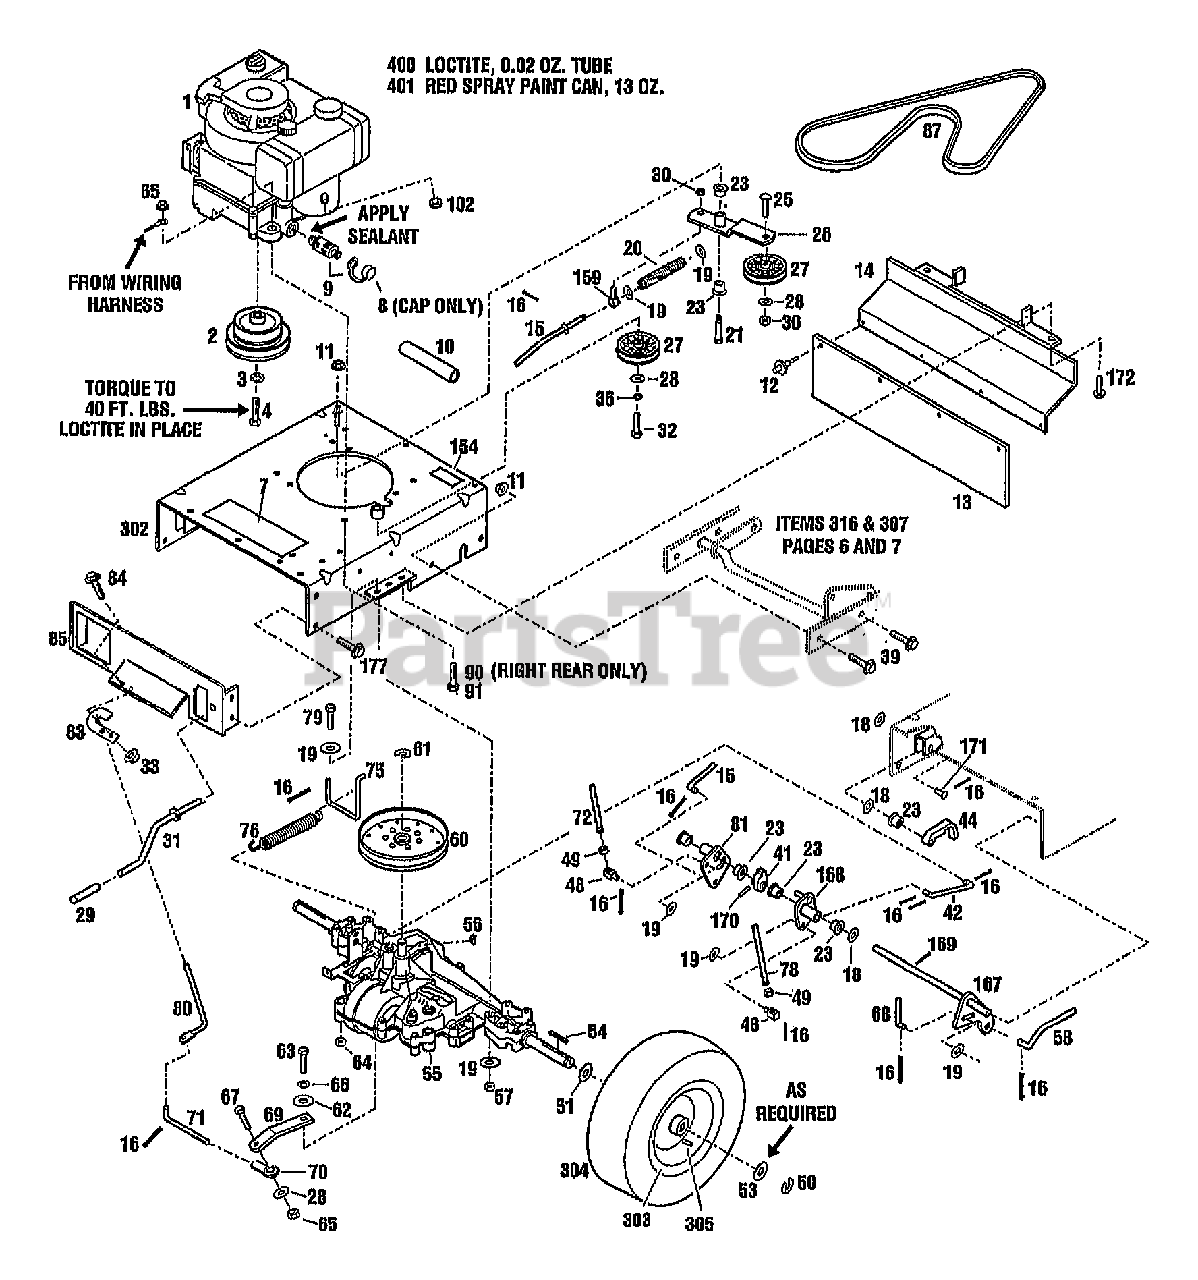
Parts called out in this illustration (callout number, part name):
1	ENGINE, 8.5HP MODEL 196707-0155 (34071,34074)
1	ENGINE, 8.5HP MODEL 196702-0142 (34073,34075)
2	PULLEY-ENGINE
3	WASHER-LK .438 ZP
4	SCR-HHC 7/16-20X1.75
7	DECAL-WARNING
8	CAP-OIL DRAIN
9	ASSM-OIL VALVE
10	HOSE-OIL DRAIN
11	NUT-HFLK 3/8-16 ZP
12	RIVET-POP 3/16 X 5/8
13	FLAP-SAFETY
14	BRACKET-FLAP
15	ROD-LOWER TRANS
16	PIN-COTTER .093X.625
18	WASHER-FLAT .88X.5X.06 ZP
19	WASHER-FLAT 5/16 SAE
20	SPRING-COMPRESSION
21	SCR-SHLDR 3/8-16
23	BUSHING-.5X.5 NYLON FLNG
25	SCR-CARR 3/8-16X1.75 G5 ZP
26	ASSM-IDLER ARM ZP
28	WASHER-FLAT 3/8 SAE
29	GRIP-PLASTIC
30	NUT-LOCK 3/8-16
31	ASSM-CRANK LIFT
32	SCR-HH 3/8-16X1.75 G5 ZP
33	NUT-HF/LK 1/4-20 ZP
36	WASHER-LK .375 @ DEPL
39	SCR-HFLK 3/8-16X1.00 ZP
41	CAM-INTERLOCK
42	ROD-LOWER BRAKE
44	LATCH-INTERLOCK
48	BLOCK-SWIVEL ZP
49	NUT-HEX JAM 5/16-18
50	RING-RET."E".577 ID
51	WASHER-1.5X.755X.062
53	WASHER-1.25X.765X.049
54	KEY-.188 SQ X 2.25
55	TRANSMISSION ASSEMBLY, MODEL 915-027 (SEE GRIDS E-5, E-6 FOR BREAKDOWN)
56	KEY-WOODRUFF .188X.75
57	NUT-TOP/LK 5/16-18 ZP
58	ROD-LOWER BLADE
60	PULLEY-TRANSAXLE
61	RING-RETAIN .625 ID
62	WASHER-FLAT 1/4 SAE
63	SCR-HH 1/4-28X.75 G5 ZP
64	NUT-HFLK 5/16-18 ZP
65	NUT-H/LK 3/8-16
66	WASHER-LK .25 ZP
67	SCR-HH 3/8-16X1.25
68	ROD-UPPER BLADE
69	ARM-TRANSMISSION ZP
70	JOINT-BALL
71	ROD-SHIFT LINK
72	ROD-UPR TRANSMISSION
75	ROD-SPRING ATTACHMENT
76	SPRING-EXTENSION
78	ROD-UPPER BRAKE
79	SCR-HH 5/16-18X2.75 G5 ZP
80	LEVER-SHIFT
81	ASSM-CLUTCH ARM ZP
83	BRKT-SHIFT ROD MTG
84	SCR-HFLK 1/4-20X.50 ZP
85	PLATE-BACK
90	SCR-THRD FRM 3/8-16X1.50
91	SCR-HH 3/8-16X1.0 THDFM
102	NUT-HEX 1/4-20 ZP
154	DECAL-AMERICAN LEGEND-SM
159	BOLT-EYE
167	SHAFT-PIVOT ZP
168	ASSM-BRAKE ARM ZP
169	PIN-COTTER .120X1.00 ZP
170	PIN-ROLL .156X1.0
171	PIN-CLEVIS .5X1.25
172	SCR-HFLK 5/16-18X.75
177	SCR-HFLK 5/16-18X.625 STH
302	ASSM-FRAME
304	TIRE
305	STEM-VALVE
400	LOCTITE-242 (.5 ML TUBE)
401	PAINT-RED SPRAYCAN POWDER
